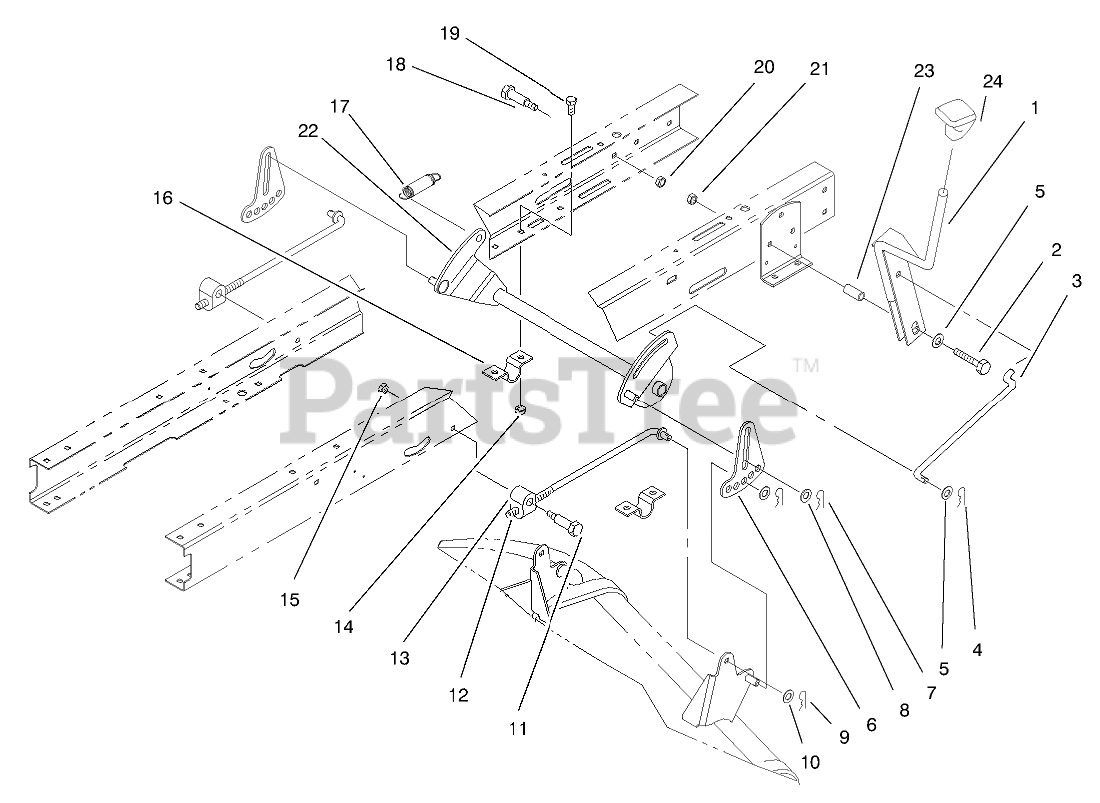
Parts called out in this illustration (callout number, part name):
1	HOC LEVER ASM
2	SCREW-HH
3	LINK-HOC
4	PIN-COTTER
5	WASHER-FLAT
6	LINK-ADJUSTING, HOC
7	PIN-COTTER
8	WASHER-HARDENED
9	PIN-COTTER
10	WASHER-FLAT
11	SCREW-SHOULDER, HH
12	ROD-HANGER, REAR
13	TRUNNION-HOC
14	NUT-LOCK, NI
15	NUT-LOCK, NI
16	CLAMP-PIVOT, HOC
17	SPRING-EXTENSION
18	SCREW-SHOULDER, HH
19	SCREW-HH
20	NUT-LOCK, NI
21	NUT-LOCK, NI
22	PIVOT ASM
23	SPACER
24	KNOB-SHIFT
